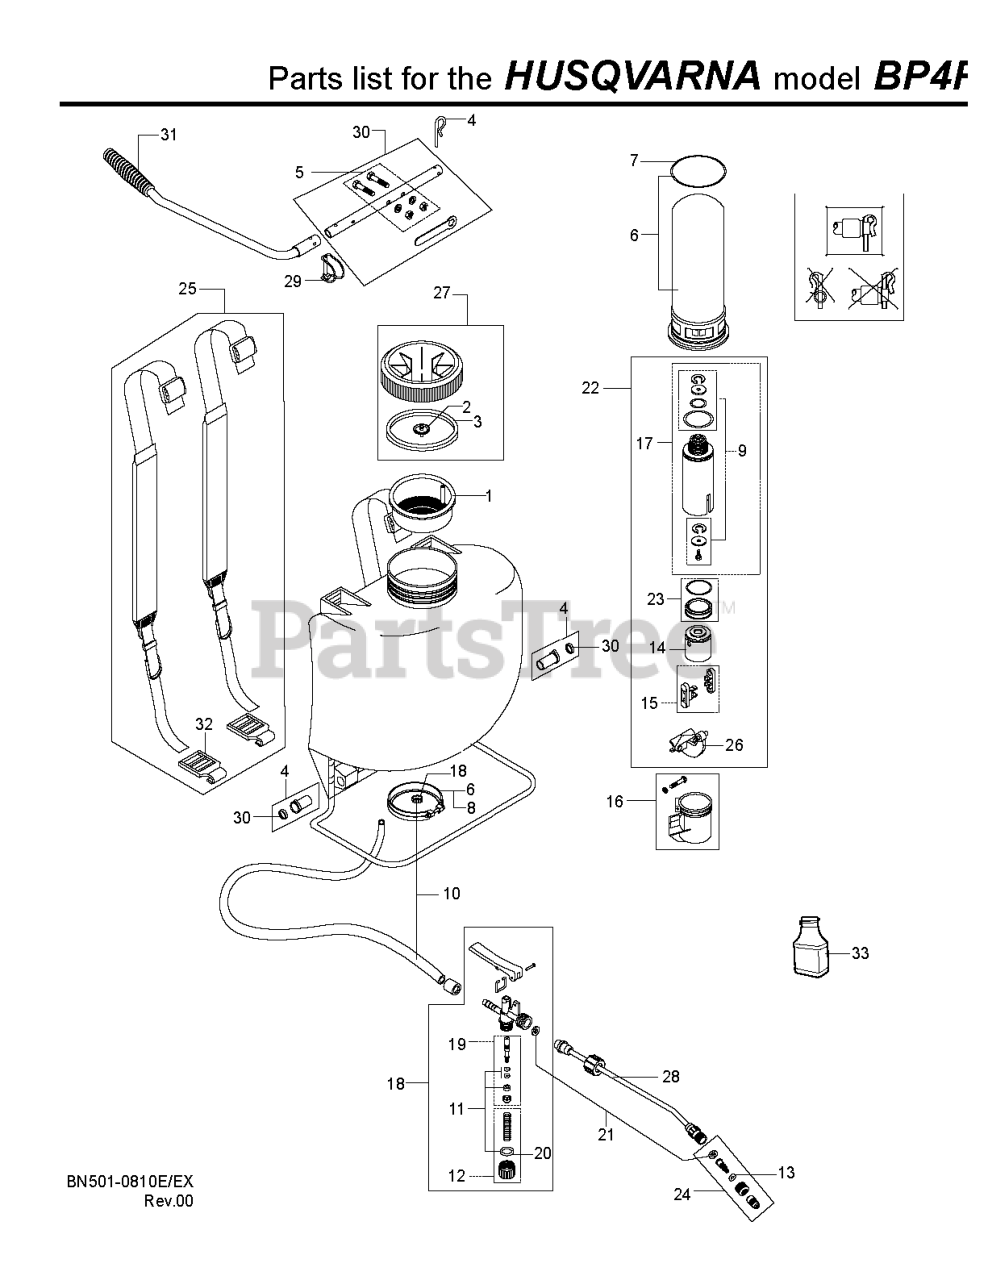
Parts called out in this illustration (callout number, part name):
1	TANK STRAINER
2	CHECK VALVE FOR CAP
4	NYLON BEARING
5	SCREW AND NUT SET
6	TANK PRESSURE
7	PRESSURE TANK O-RING
8	CLAMP PLASTIC RETENTION
9	O-RING & WASHER SET FOR DIAP
10	HOSE AND 2 HOSE CLAMPS
11	SPINDLE O-RING SET
13	SPRAY TIP O-RING SET
14	PISTON ONLY WITH BRASS PIN
15	CONNECTING ROD ASSY
16	PISTON PROTECTOR COMPLETE
17	CYLINDER ASSY
18	SPRAY GUN W/GRIP & PLASTIC HND
19	SPINDLE PLASTIC COMPLETE
20	O-RING PLUG
21	WASHER SET FOR GUN & NOZZLE
22	G8 PISTON & CYLINDER COMPLETE
23	PISTON CUP G8
24	PLASTIC NOZZLE ADJ W/O-RINGS
25	RP SHOULDER STRAP PADDED AJ
27	LID ORANGE 6"
28	SPRAYER
29	PIN CLEVIS W/LOCKING RING
30	PUMP LEVER
31	PUMP HANDLE
33	SILICONE GREASE ALL SPRAYERS
